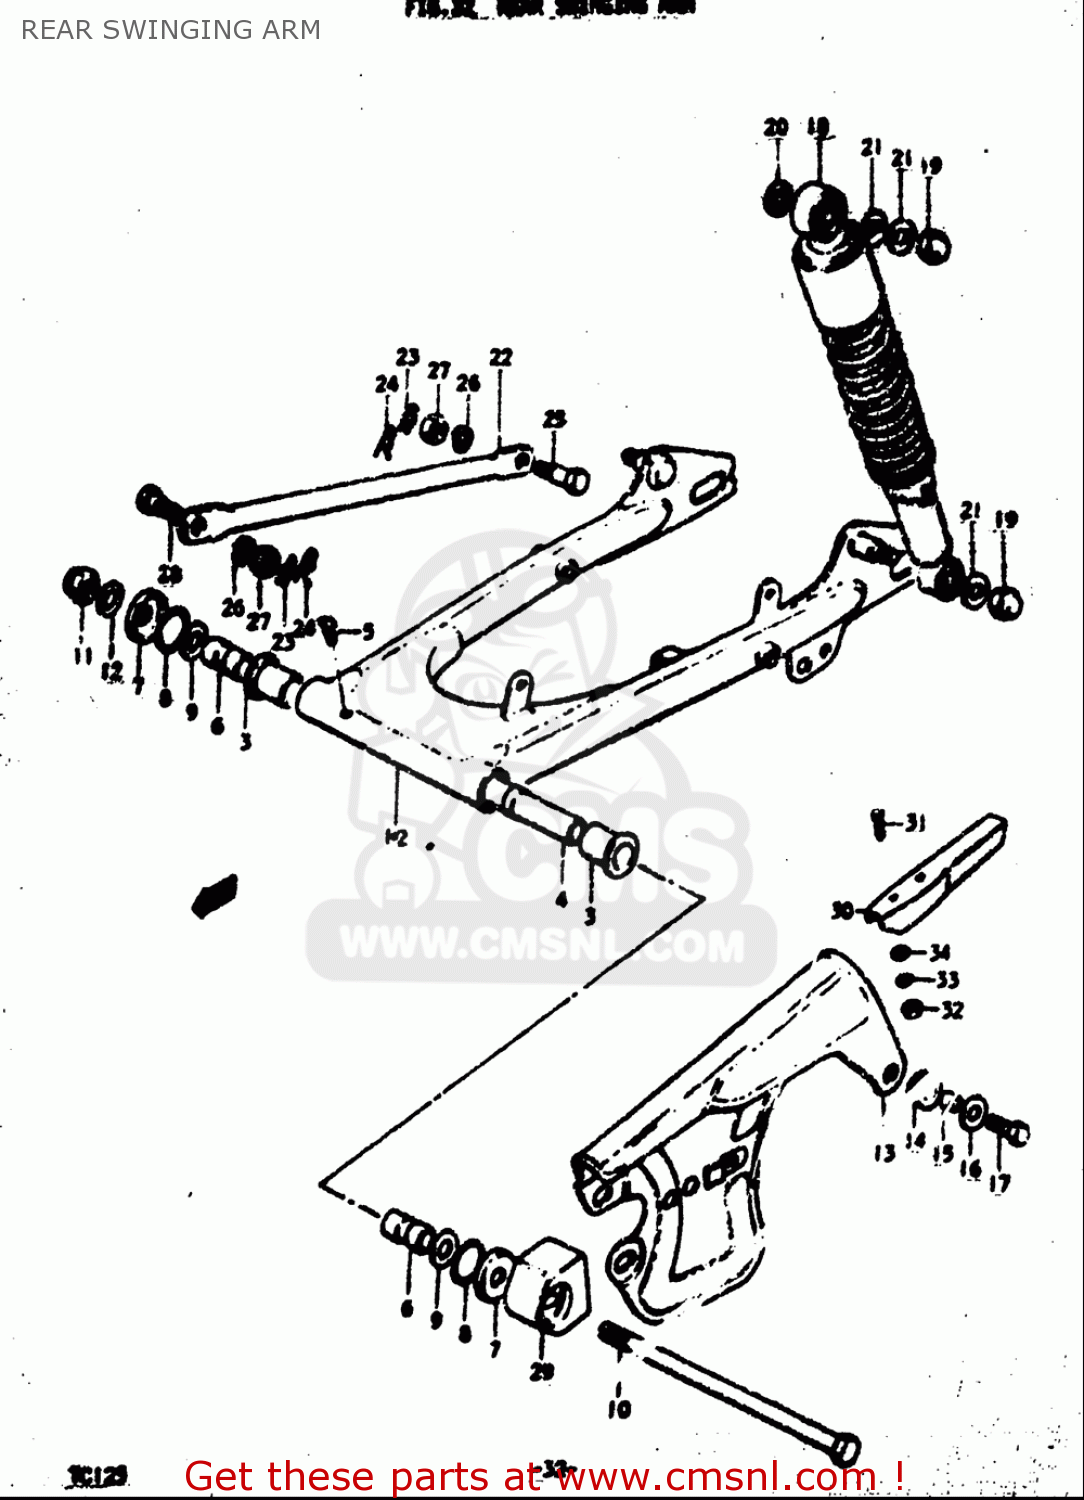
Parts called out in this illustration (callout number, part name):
3	BUSH
4	SPACER,SWING ARM,CENTER
5	NIPPLE,GREASE
6	SPACER,RR SWGARM PIVOT
7	COVER,SWGARM BUSH DUST SEAL
8	O RING(D:2,ID:24.5)
9	WASHER(12.5X26X2.3)
10	SHAFT,PIVOT
11	NUT
12	WASHER
14	CUSHION
15	SPACER,6.5X9X7
16	WASHER(6.5X20X1.2)
17	BOLT
19	NUT
20	WASHER
21	WASHER (10.5X24X2.3)
22	LINK,RR TORQUE
23	RETAINER,SNAP
24	CLIP
25	BOLT(8X26.5)
26	WASHER,LOCK
27	NUT
28	BOLT(8X22)
29	BUFFER,CHAIN TOUCH DEFENSE
31	BOLT
32	NUT
33	WASHER,LOCK
34	WASHER
